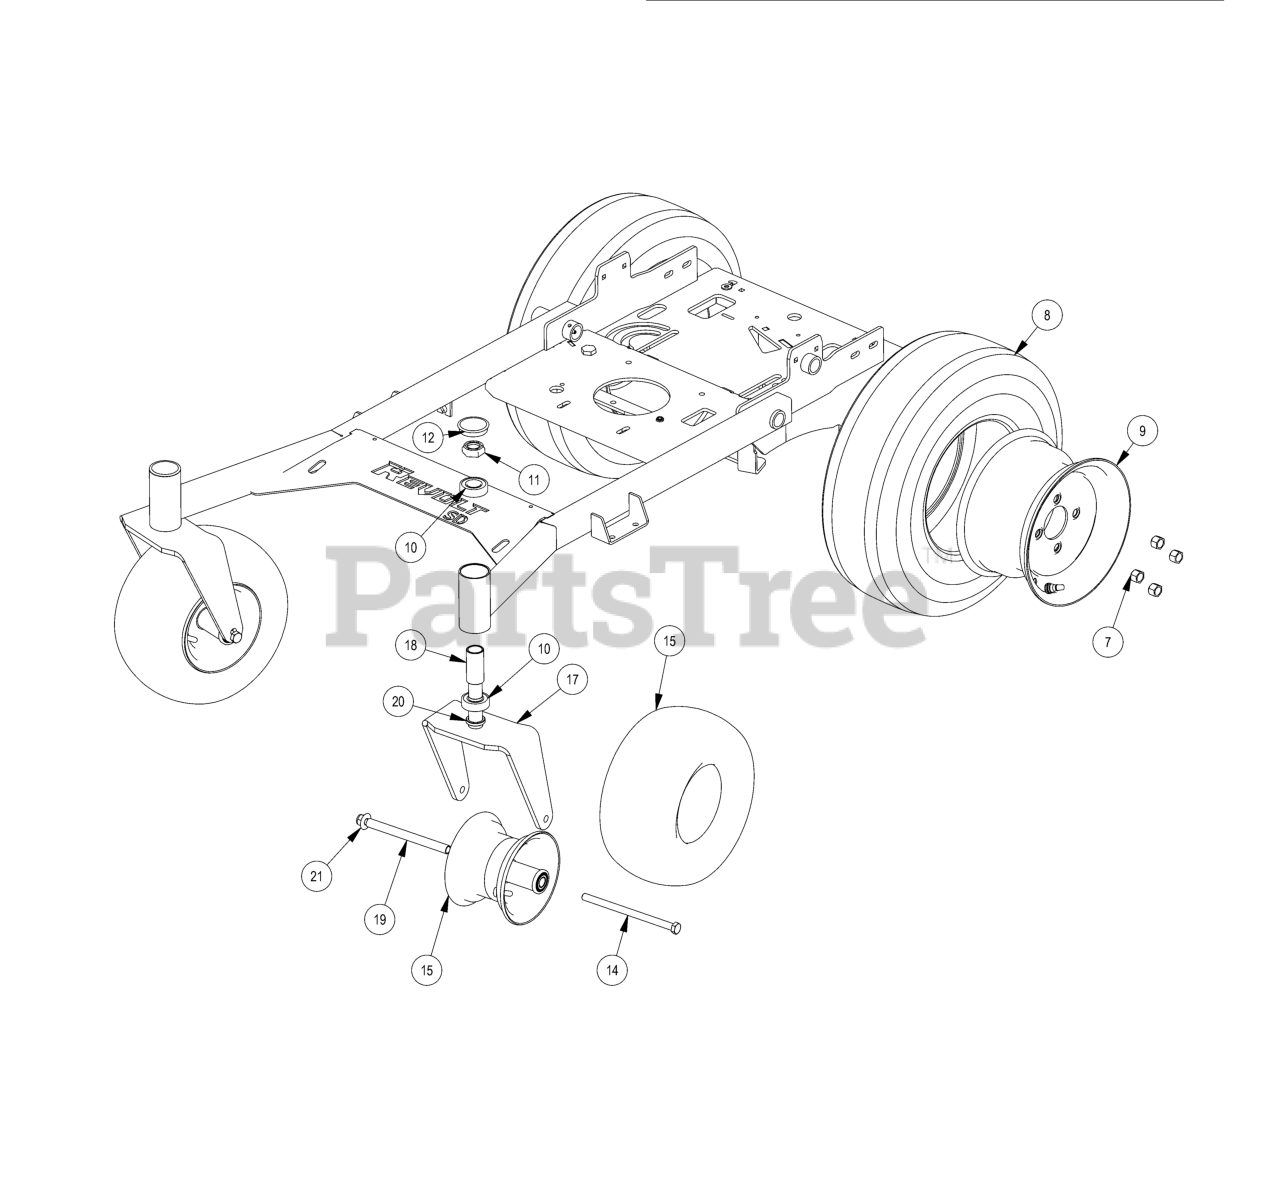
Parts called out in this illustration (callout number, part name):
1	5/16-18 Nylock Jam Nut
2	1/2-13 Nylon Insert Nut
3	1/2 Flat Washer
4	1/4 DRIVE-TYPE STRAIGHT GREASE FITTING (NO BALL) ZINC
5	2023 Stand On Frame Weldment -SD
6	1/4 USS FLAT WASHER (3/4 OD) ZINC
7	Acorn Lug Nut
8	36" Revolt Reaper Tire
9	36" Revolt Wheel
10	1641 BEARING W/2 CONTACT RUBBER SEALS
11	1" Fine Thread 1/2 Nylock Nut
12	2017 Bearing Cover
13	1-14 x 5 Hex Bolt Grade 8 Zinc Yellow
14	1/2" x 8 1/2 GR 5 Hex Bolt
15	13x6.5-6 Black Tire and Wheel Assembly
16	1 3/8" Wheel Bearing
17	2017 ZT Front Fork
18	2016 Front Bearing Spacer
19	Front Wheel Spanner
20	Spacer, 1x1.375x.25
21	1/2-13 Nylon Flange Nut
